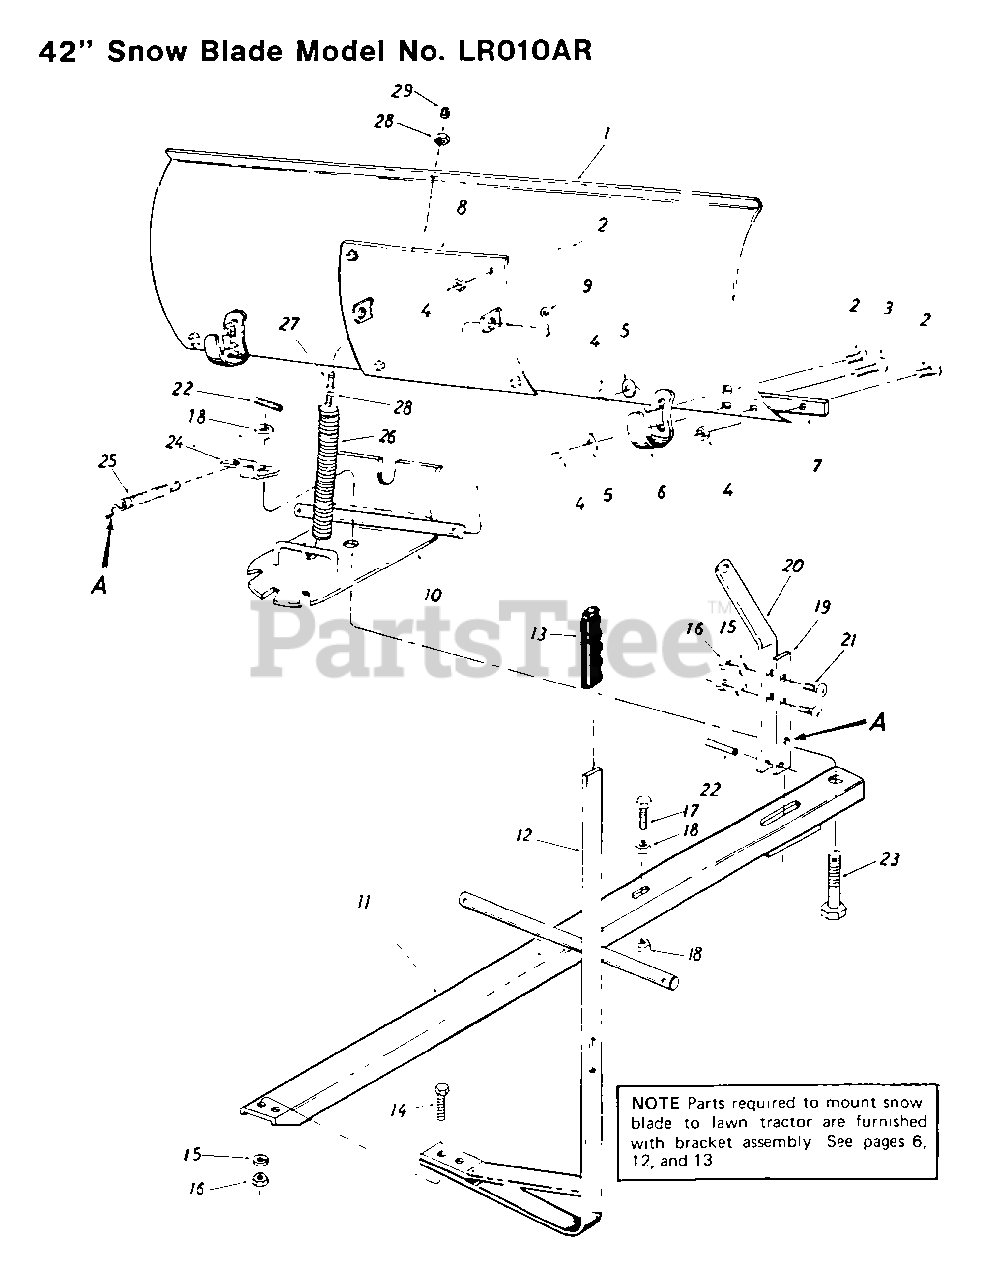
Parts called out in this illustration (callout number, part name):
10	PIVOT PLATE ASSY
11	CHANNEL ASSY
12	LIFT HANDLE ASSY
13	HANDLE GRIP
19	BAR ANGLE LO
